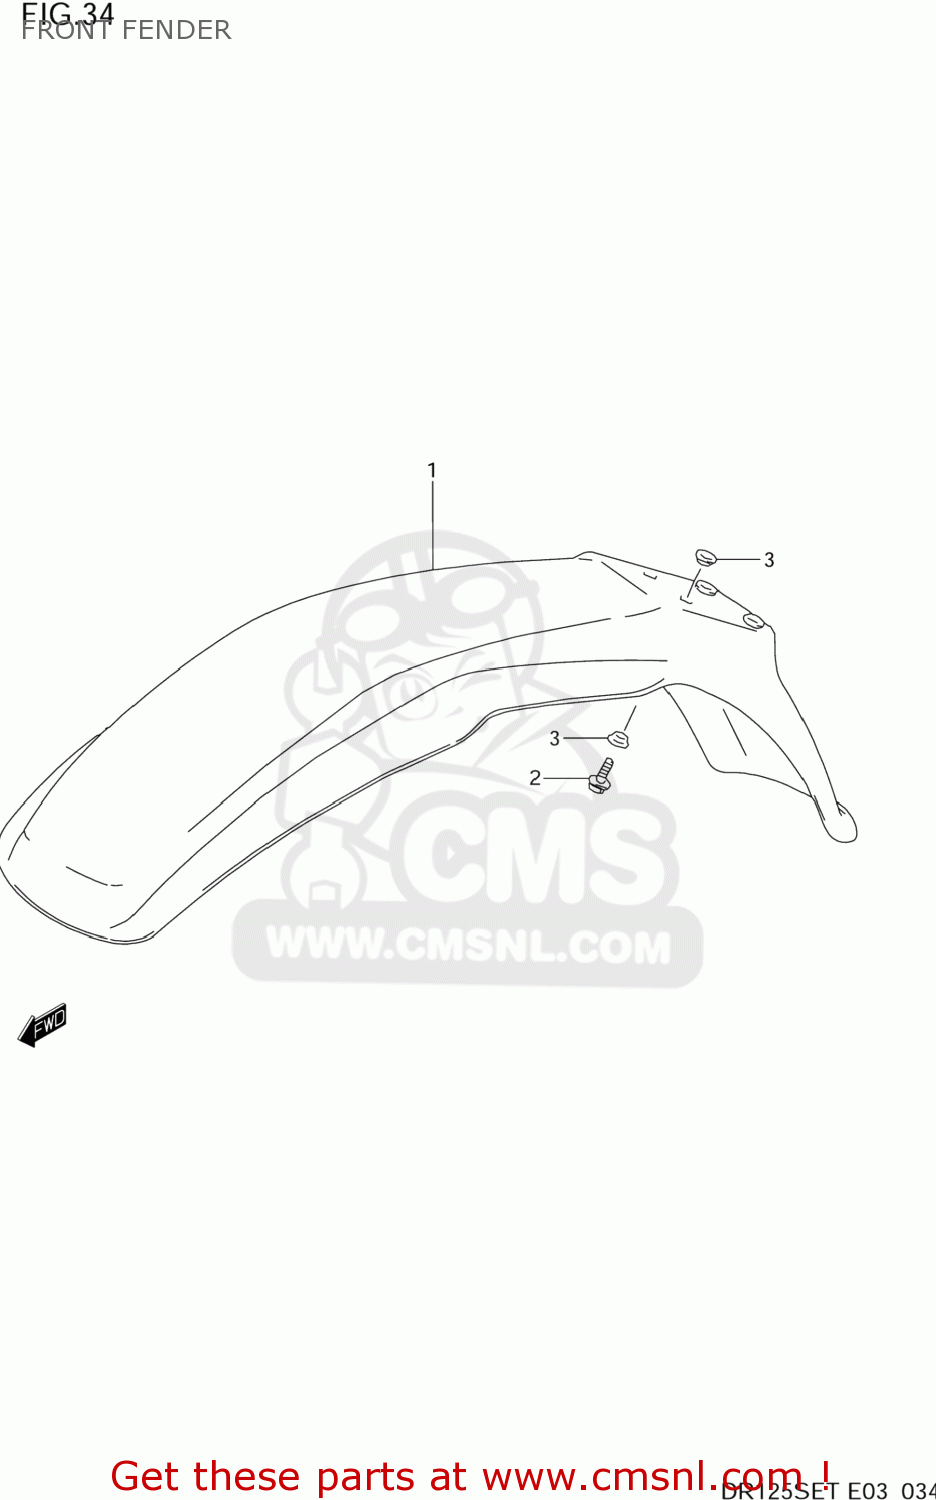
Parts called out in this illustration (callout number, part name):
1	FENDER,FR
2	BOLT
3	WASHER
